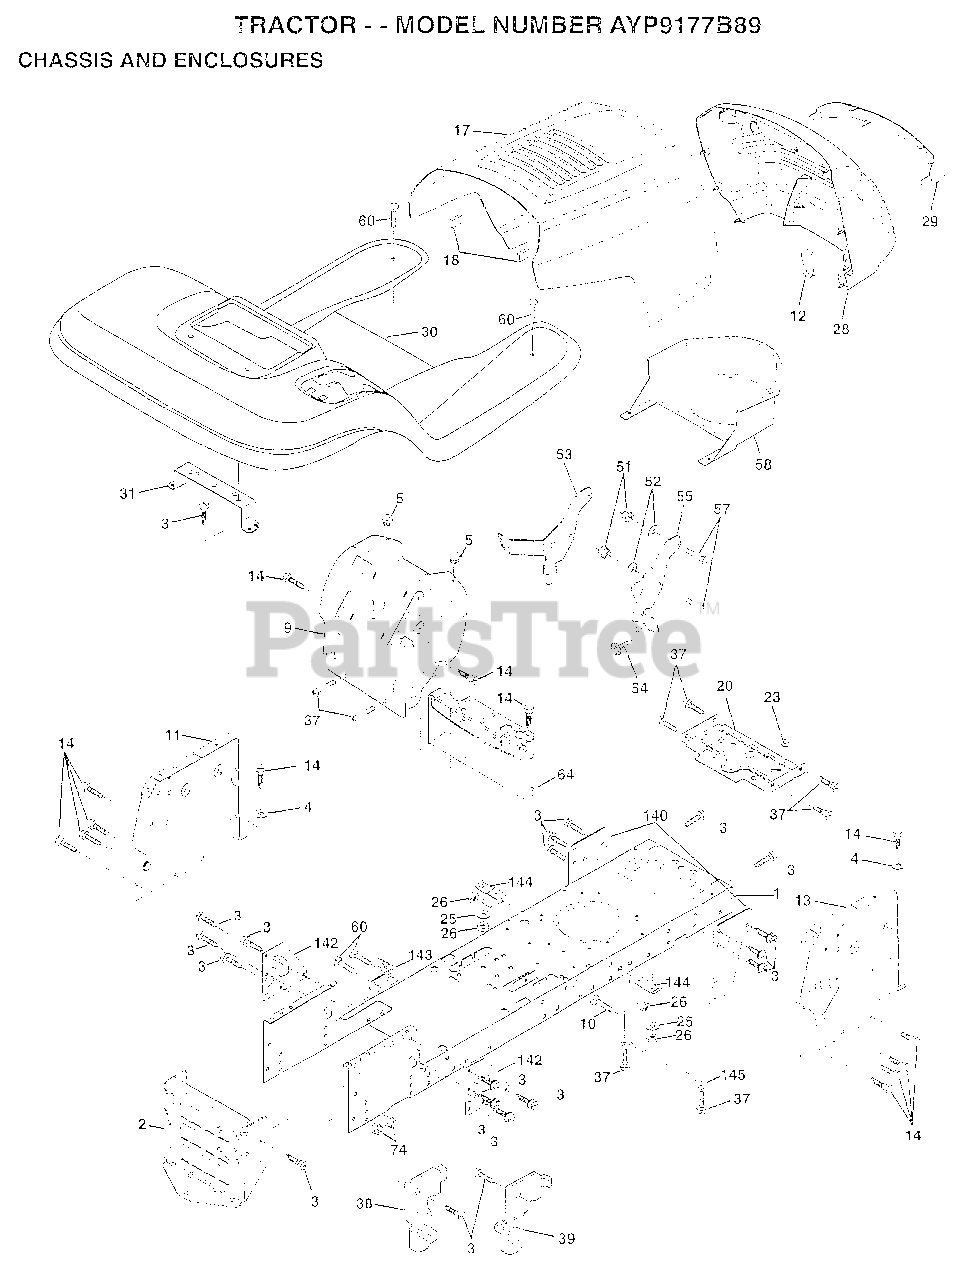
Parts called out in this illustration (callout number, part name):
1	CHASSIS
3	SCREW
4	WASHER
5	BUMPER-HOOD/DASH
11	"PANEL-DASH,LH"
12	CLIP.TINNERMAN
13	"PANEL-DASH,RH"
14	SCREW LT
17	HOOD.STEEL.ASSY
20	"PLATE-MTG,BATT/FU"
25	WASHER
26	NUT
28	GRILL
29	LENS.EURO.W/DECAL
30	FEND/FTREST PNT
31	BRACKET SUPT FEND
38	BRACKET ASM LH
39	BRACKET ASM RH
51	NUT
52	WASHER
53	BRACKET.GRILLE.LH
54	SCREW.HEX.WS.HD
55	BRACKET.GRILLE.RH
58	AIR DUCT
60	BOLT
64	DASH-LOWER
140	BRKT SUSPENSION
142	PLATE.REINFORCEMT
143	"BRKT-S'BAR,CHASSI"
145	"ROD POVOT,CHASSIS"
